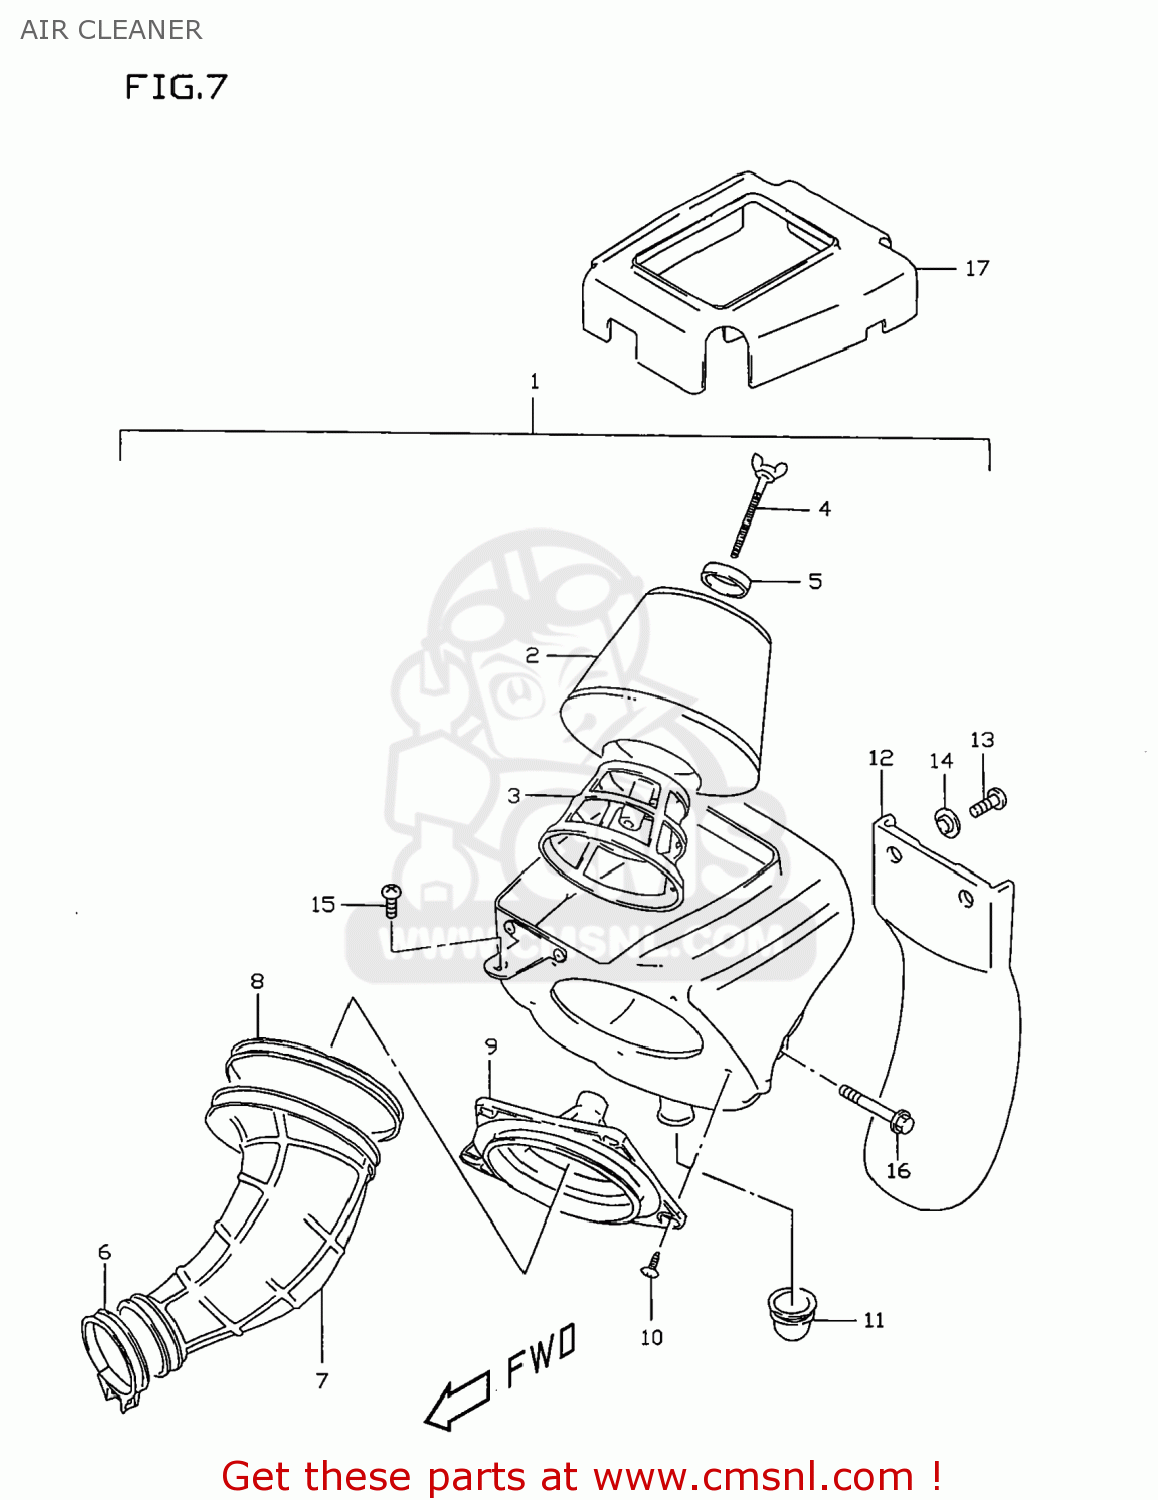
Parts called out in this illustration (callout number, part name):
1	CLEANER ASSY,AIR
2	FILTER ASSY
3	HOLDER
4	BOLT,WING
5	WASHER,AIR CLEANER
6	CLAMP
7	TUBE,OUTLET
8	CLAMP
9	BASE,FILTER
10	SCREW
11	HOSE,AIR CLEANER DRAIN
12	GUARD,MUD
13	SCREW
14	COLLAR
15	SCREW 6X12
16	BOLT
17	MUD GUARD,B
